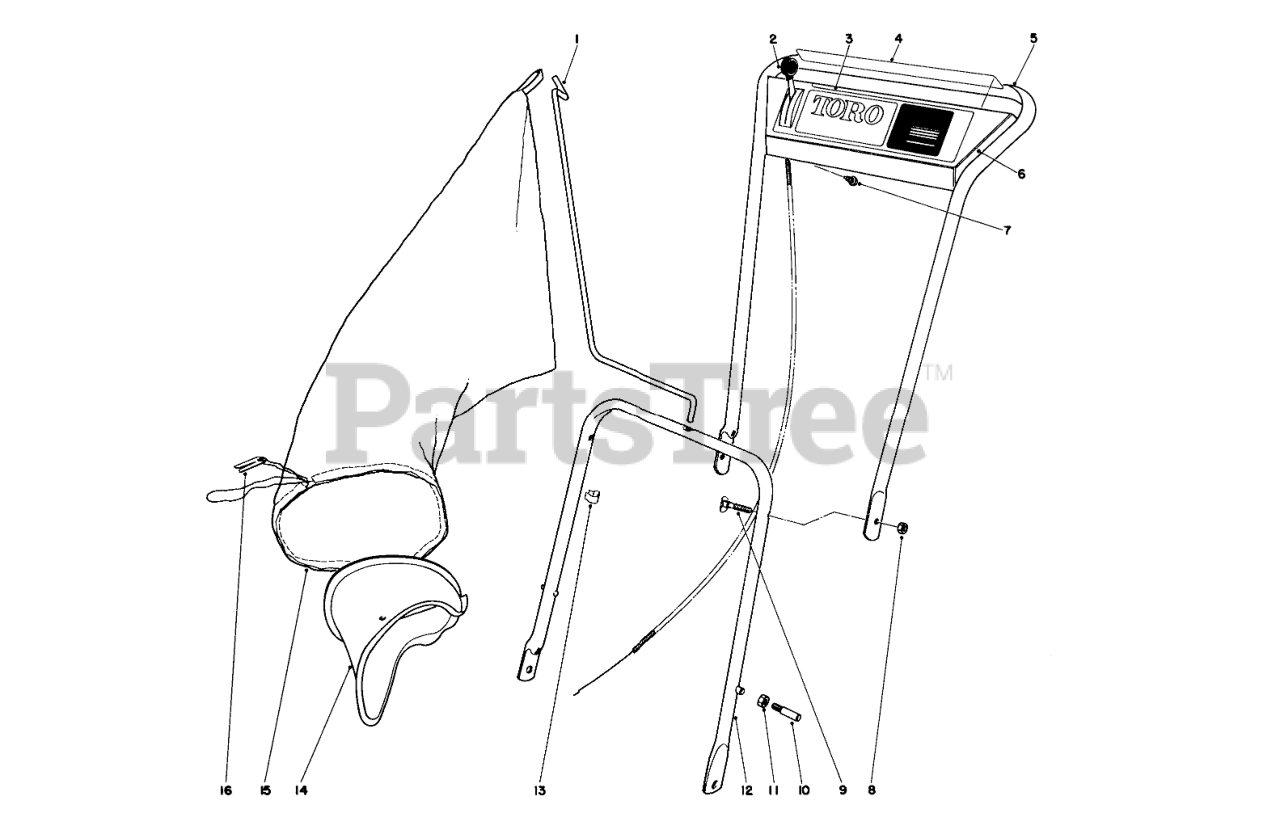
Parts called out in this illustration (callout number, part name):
1	BAG HANGER ROD
2	Throttle Control
3	Escutcheon Plate Decal
4	Decal, Safety
5	UPPER HANDLE
6	Escutcheon Panel
7	SCREW-HWHTF
8	Nut
9	Handle Screw
10	HANDLE PIN
11	Nut
12	LOWER HDLE STKD ASM
14	BAG ATTACHMENT
15	Grass Bag (Incl. Ref.16)
16	BAG CORD FASTENER
